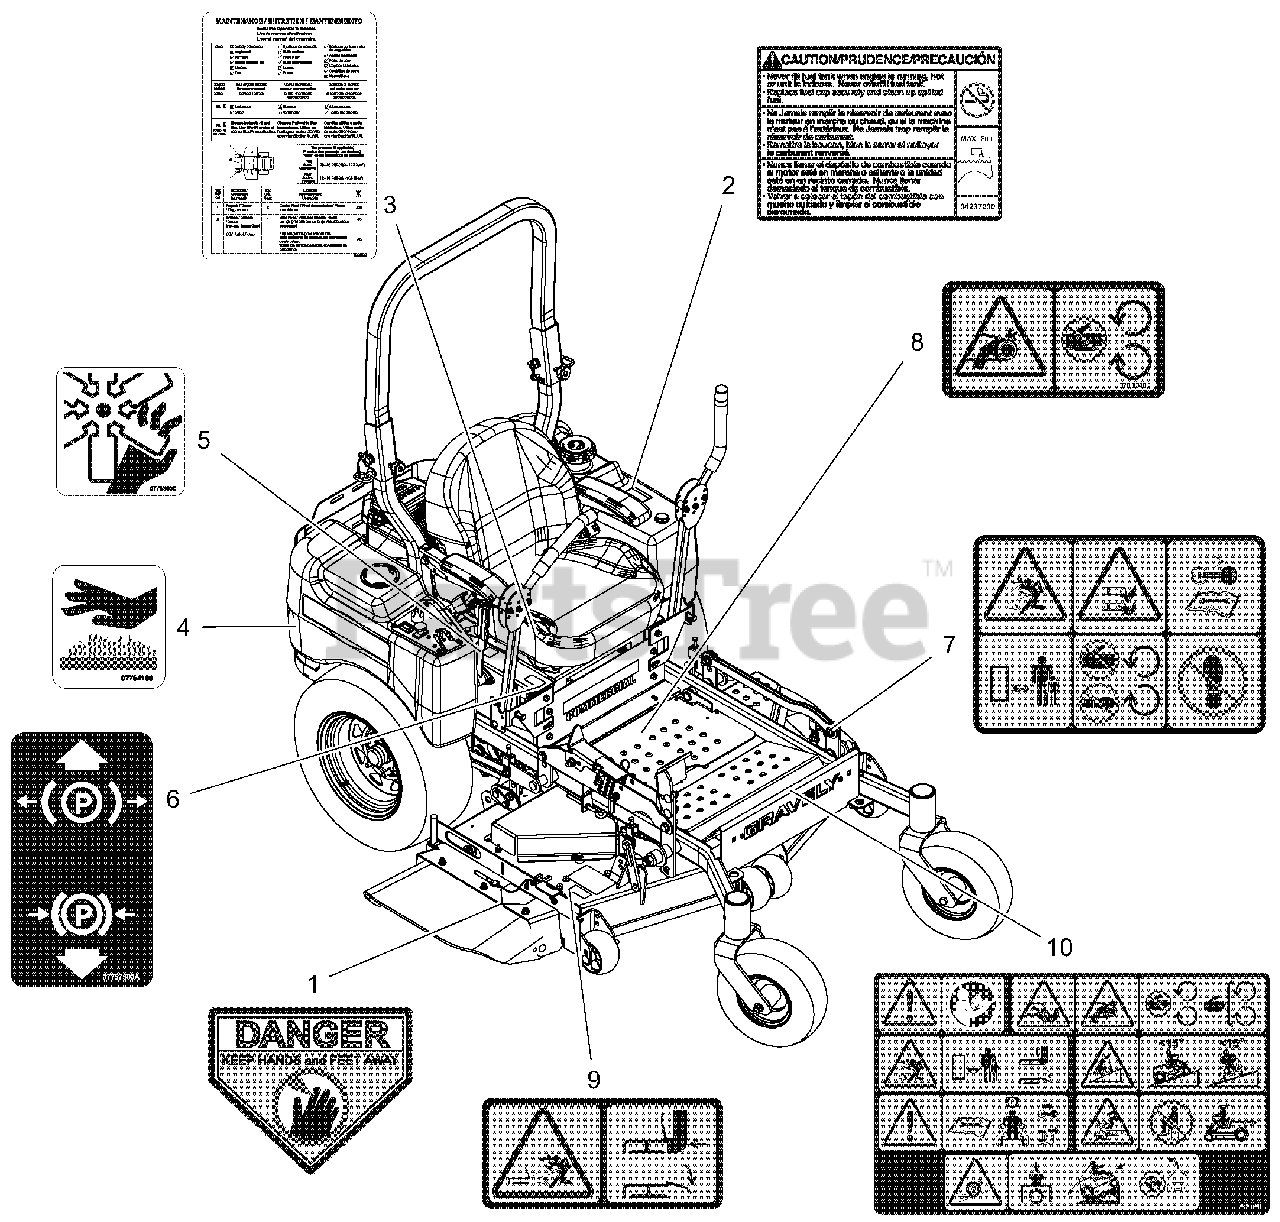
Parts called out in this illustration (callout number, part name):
1	DECAL, DANGER
2	DECAL, FUEL WARNING
3	DECAL, MAINTENANCE INSTRUCTIONS
4	DECAL HOT SURFACE
5	DECAL, DANGER - FAN
6	DECAL, PARKING BREAK LEVER
7	DECAL, SAFETY - MOWER DECK
8	DECAL, SAFETY - GUARDING
9	DECAL, SAFETY - DECK GUARDING
10	DECAL, MAIN SAFETY, COMMERCIAL
